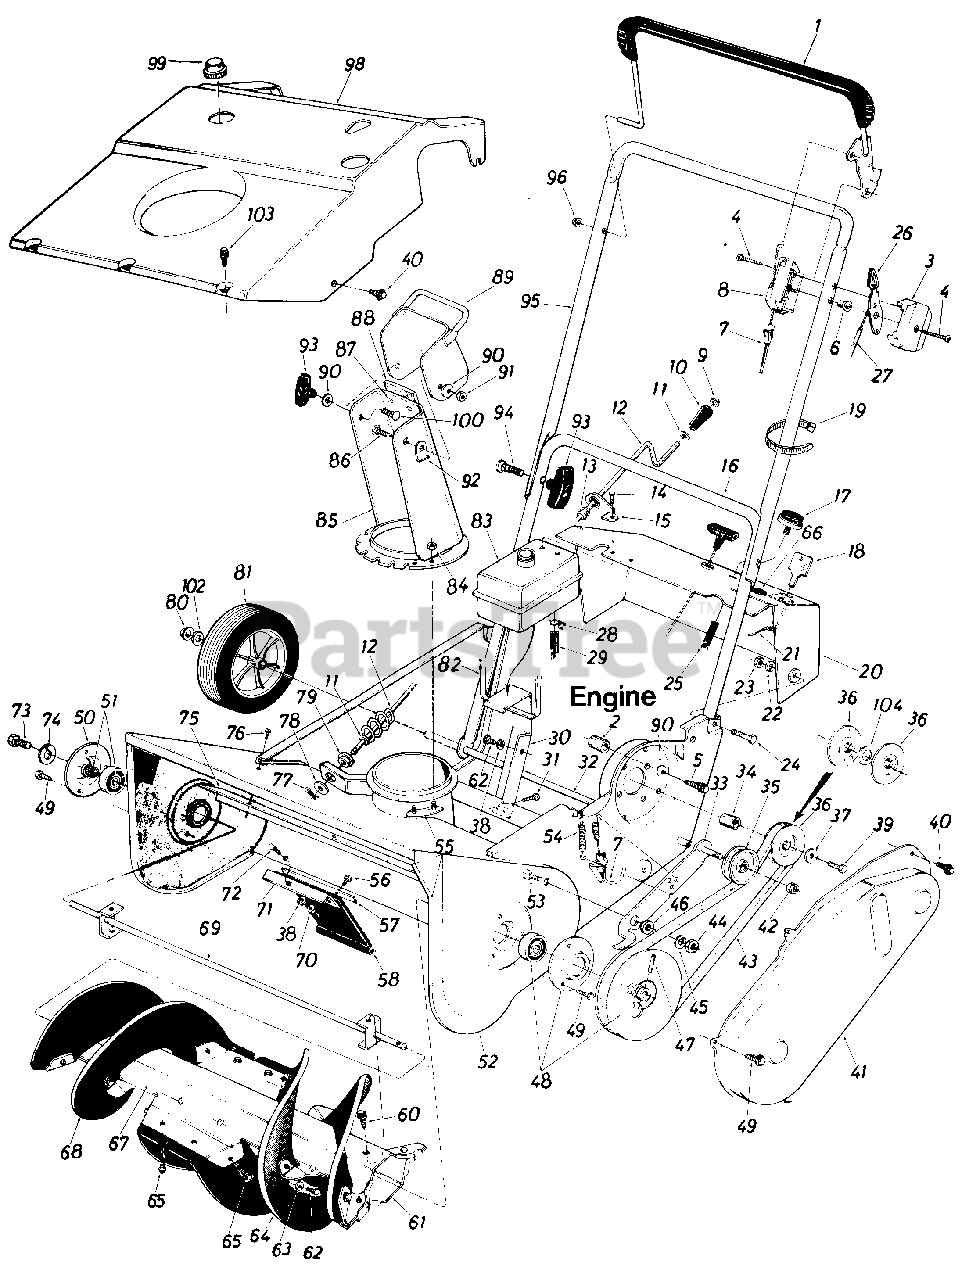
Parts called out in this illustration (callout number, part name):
1	Clutch Control Handle Ass'y.
2	Spacer.325" I.D. x .625" O.D.
3	Control Panel Half
4	Truss Mach. Hi-B Tap Scr. #12 x 1.50" Lg.
5	Hex Bolt 5/16-18 x 1.50" Lg.
6	Control Disc Pin
7	Clutch Cable 35" Lg. Black
8	Clutch Panel Half
9	Push Nut 3/8 Rod
10	Knob Black 3/8" Dia. Hole
11	Fl-Wash. .385" I.D. x .62" O.D.
12	Chute Crank Ass'y.
13	Chute Crank Grommet
14	Hex Tap Scr. 1/4" x .75" Lg.
15	Upper Chute Crank Brk't.
16	Lower Handle
17	Primer
18	Starter Key
19	Cable Tie
20	Dash Panel Ass'y.
21	Ignition Wire
22	L-Wash. 5/16" I.D.
23	Hex Nut 5/16-18 Thd.*
24	Hex Bolt 5/16-18 x 1.50" Lg.
25	Primer Hose 118" I.D. x 11"
26	Throttle Lever
27	Throttle Wire
28	Hose Clamp .406" Dia.
29	Gas Line 9" Long
32	Wheel Axle
33	Idler Brake Brk't. Ass'y.
34	Spacer
35	Fl-Idler 2.00" x 1" w/Flange
36	3/8" V-Pulley .625" I.D. x 2.25
37	Bell-Wash. .345" I.D. x .88"
38	L-Wash. 1/4" I.D.
39	Hex Scr. 5/16-24 x .75" Lg.
40	Hex L-Wash. Hd. AB-Tap Scr. 1/4 x .62"
42	Hex L-Nut 3/8-24 Thd.
43	V-Belt 1/2" x 34" Lg.
44	Hex Nut 5/16-18 Thd.
45	L-Wash. 5/16" I.D.
46	Shld. Spacer 1.0" O.D. x .315 I.D.
47	Spring Pin Spir. 114" Dia. x 1.00" Lg.
48	Kit-Bearing, Cup and Pulley
49	Hex "B"-Tap Scr. 1/4-20 x .38" Lg.
52	Blower Housing Ass'y.
53	Truss. Mach. Scr. 5/16-18 x .75" Lg.
54	Extension Spring .33" O.D.
55	Chute Flange Keeper Ass'y.
56	Hex Wash. AB-Tap Scr. 1/4" x .62" Lg.
57	Retaining Strip 19.0" Lg.
58	Rear Flap 4.69" x 18.2"
60	Hex L-Wash. Hd. AB-Tap Scr. 1/4 x .62" Lg.
61	Auger Half 21.0" Lg.
62	Hex Wash. Hd. Self-Tap Scr. 1/4-20 x .50" Lg.
63	Fl-Wash. .28" I.D. x .74" O.D.
64	8.5" Dia. Rubber Spiral
65	Hex B-Tap Scr. 1/4 x .62" Lg.
66	Plastic Plug
67	Auger Half 21.0" Lg.
68	8.5" Dia. Rubber Spiral
69	Auger Axle Ass'y.
70	Hex Nut 1/4-20 Thd.
71	Shave Plate
72	Carriage Bolt 1/4-20 x .50"
73	Hex Wash. TT-Tap Scr. 1/4-20 x .75" Lg.
74	L-Wash. 1/4" I.D.
75	Thrower Housing Angle
76	Hex "B"-Tap Scr. 1/4" x .38" Lg.
77	Cotter Pln 3/32" Dia. x .75"
78	Fl-Wash. .385" I.D. x 1.5" O.D.
79	Hex Bushing .385" I.D.
80	Cap Speed Nut 1/2" Rod
81	Wheel Ass'y. 6 x 1.50
82	Cable Tie x 17.75" Lg.
83	Gas Tank
84	Hex Nylon L-Nut 1/4-20 Thd.
85	5.0" Dia. Chute Ass'y.
86	Carriage Bolt 5/16-18 x .62"*
87	Rivet .250" x .44" Lg.
88	Chute Seal
89	Top Chute Ass'y.
90	Bell-Wash. .345" I.D. x .88"
91	Hex Cent. L-Nut 5/16-18 Thd.
92	Top Chute Stop
93	Knob-Handle Ass'y.
94	Curved Hd. Carriage Bolt 5/16-18 x 1.75" Lg.
95	Upper Handle
96	Cap Speed Nut 5/16" Rod
98	Shroud
99	Gas Tank Cap
100	Carriage Bolt 5/16-18 x 1.00"
102	Fl-Wash. .75" O.D. x .50" I.D.
103	Hex AB-Tap Scr. #10 x .50"
104	Fl-Wash. .635" I.D. x .93" O.D.
